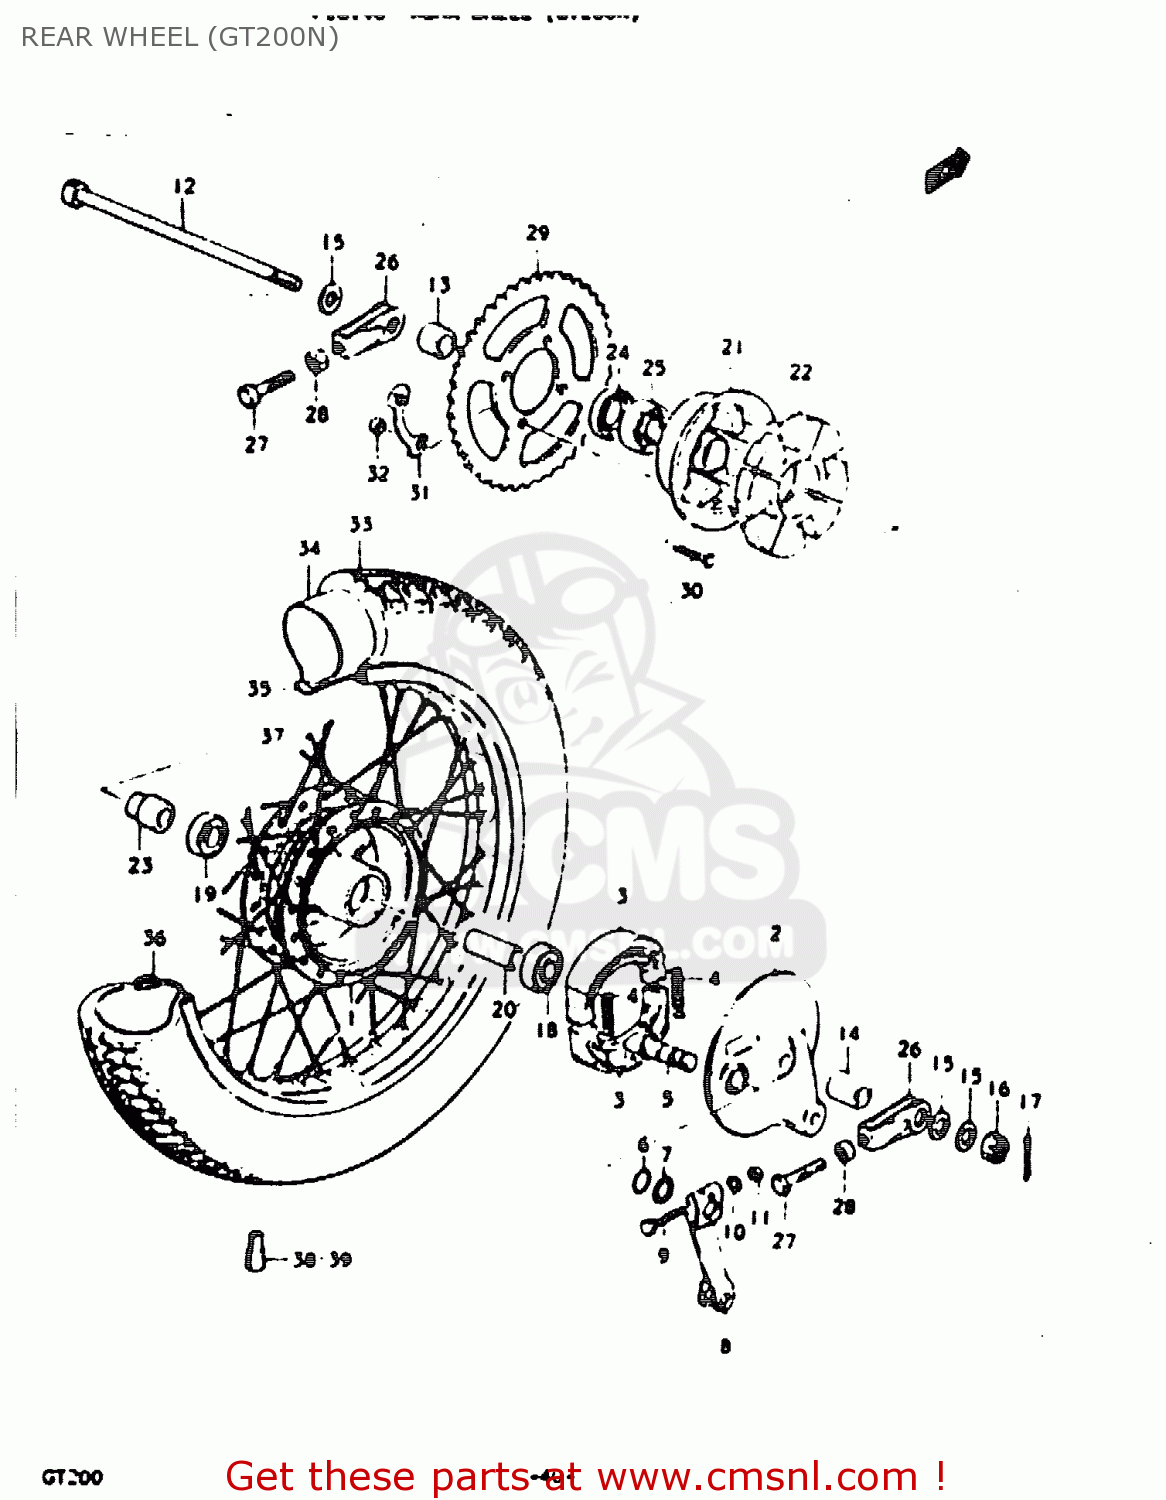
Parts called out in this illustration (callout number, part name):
1	HUB,REAR WHEEL
2	PANEL, REAR WHEEL
3	SHOE,BRAKE
4	SPRING(L:34)
5	CAM,FRONT BRAKE
6	O-RING (D:2.4 ID:13.8)
7	WASHER (14.5X22X1.6)
8	LEVER,RR BRAKE CAM
9	BOLT(6X33)
10	WASHER
11	NUT
12	AXLE,REAR
13	SPACER(15X28X19)
14	SPACER(15.2X26X33)
15	WASHER
16	NUT
17	COTTER PIN
18	BEARING
19	BEARING
20	SPACER(15.3X21.7X63)
21	DRUM,RR SPROCKET
22	ABSORBER ASSY,HUB SHOCK
23	RETAINER,RR SPROCKET MTG
24	OIL SEAL
25	Bearing
26	ADJUSTER,CHAIN
27	BOLT
28	NUT
29	SPROCKET,RR
30	BOLT(8X33.5)
31	WASHER
32	NUT
33	TIRE
34	TUBE,INNER
35	PROTECTOR,INNER TUBE
36	RIM, WHEEL
37	SPOKE SET
38	BALANCER,WHEEL (B)
39	BALANCER,WHEEL (30G)
